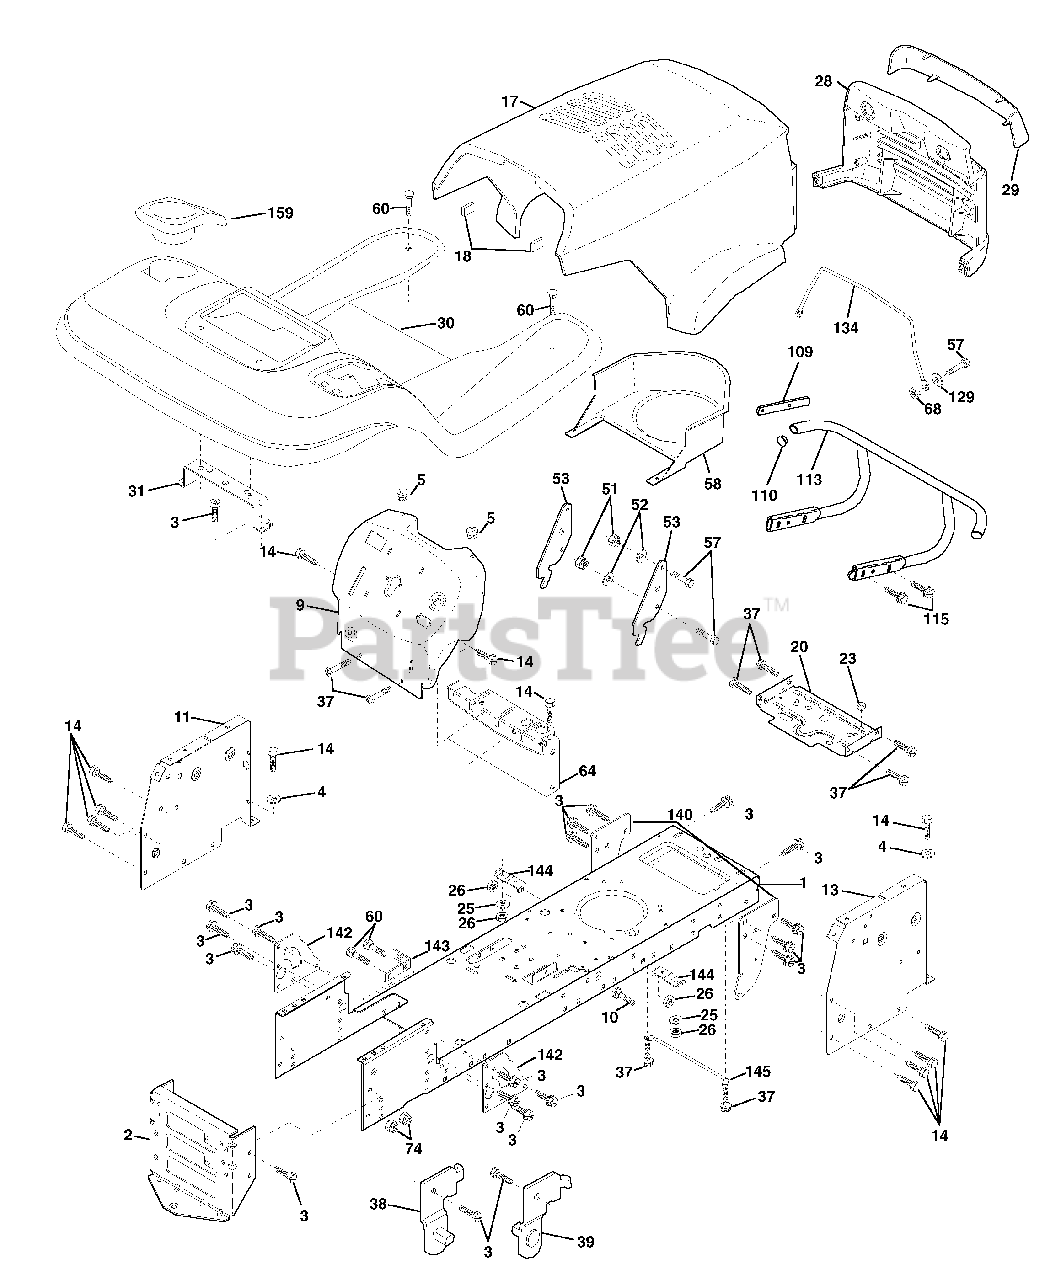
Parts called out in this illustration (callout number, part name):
1	Chassis Weldment
2	Drawbar, Stretch
3	Screw Thdrol 3/8-16x3/4 Ty-tt
4	Washer 13/32 x 3/4 x 16 Ga.
5	Bumper Hood/Dash
9	Dash Slkscr.Plm.E.A.Hm.Nc.Sym
10	Bolt Carriage 3/8-16 x 1
11	Panel Dash Lh
13	Panel Dash Rh
14	Screw Thdrol 3/8-16x1/2 Ty-tt
17	Hood LT/PL Husqvarna
18	Bumper Hood
20	Plate Mtg Battery Fuel Tank Fr
25	Washer 13/32 X 13/16 X 12 Ga
26	Nut Lock Hex W/Ins 3/8-16 Unc
28	Grille LT/PL Husqvarna
29	Lens LT/PL Husqvarna
30	Fender Footrest STLT Pnt
31	Bracket Support Fender
37	Screw Thdrol 6/16-18 x 1/2 TYT
38	Bracket, Asm. Pivot, L.H., Mower Rear
39	Bracket, Asm. Pivot, R.H., Mower Rear
51	Nut Lock Hex W/Ins 1/4-20
52	Washer 9/32 x 7/8 x 16 Ga.
53	Bracket Pnt. Pick off LT/PL Husqvarna
57	Bolt Hex 1/4-20 x 3/4
58	Air Duct Engine P/L
60	Bolt Rdhd Sqnk 3/8-16unc x 3/4
64	Dash Lower STLT
68	Nut Keps Hex 1/4-20unc
74	Nut Crownlock 3/8-16 UNC
109	Bracket Extension Bumper
110	Plug Plastic
113	Bumper Asm.
115	Screw Thdrol 3/8-16 x 1-1/4
129	Washer 9/32 x 5/8 x 16 Ga.
134	Rod Support Hood LT/PL Husq.
140	Bracket Suspension Front
142	Plate Reinforcement STLT
143	Bracket Swaybar Chassis
144	Bracket Pnt Footrest STLT
145	Rod Pivot Chassis/Hood
159	Cupholder Stlt Grey
